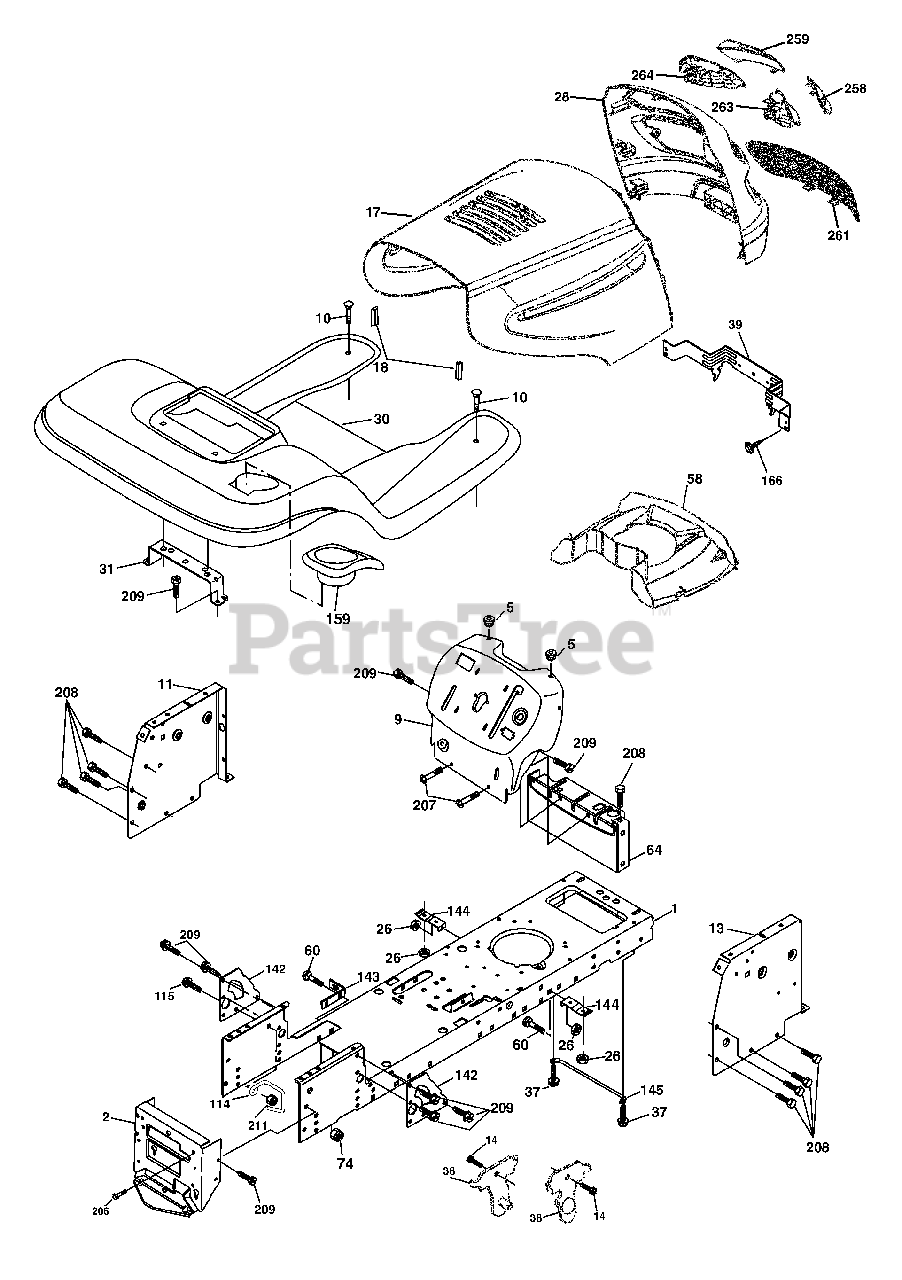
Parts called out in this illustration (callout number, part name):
1	Chassis
2	Drawbar
5	Bumper Hood/Dash
10	Bolt Carriage 3/8-16 x 1
11	Panel Dash Lh
14	Screw Thdrol 3/8-16 x 1-1/4
17	Hood
18	Bumper Hood
26	Nut Lock Hex W/Ins 3/8-16 unc
28	Grille
30	Fender/Footrest
31	Bracket Support Fender
37	Screw Thdrol 6/16-18 x 1/2 TYT
38	Bracket Asm. Pivot Mower Rear
39	Bracket Pivot
58	Duct Intake
60	bolt 3/8-16 unc x 3/4
64	Dash Lower STLT
74	Nut Crownlock 3/8-16 unc
114	Keeper Belt Rear LH
115	Screw Thdrol 3/8-16 x 1-1/4
142	Plate Reinforcement STLT
143	Bracket Swaybar Chassis
144	Bracket Footrest
145	Rod Pivot Chassis/Hood
159	Cupholder
166	Screw 10 x 3/4 Single Lead Hex
206	Bolt Shoulder 5/16-18
207	Screw Thdrol 5/16-18 x 1/2
208	Screw Thdrol 3/8-16 x 1/2
209	Screw Hex Wsh Thdr. 3/8-16 x 3/4
211	Nut Hexflange Lock
258	Lens RH
259	Lens LH
263	Bezel Grille RH
264	Bezel Grille LH
